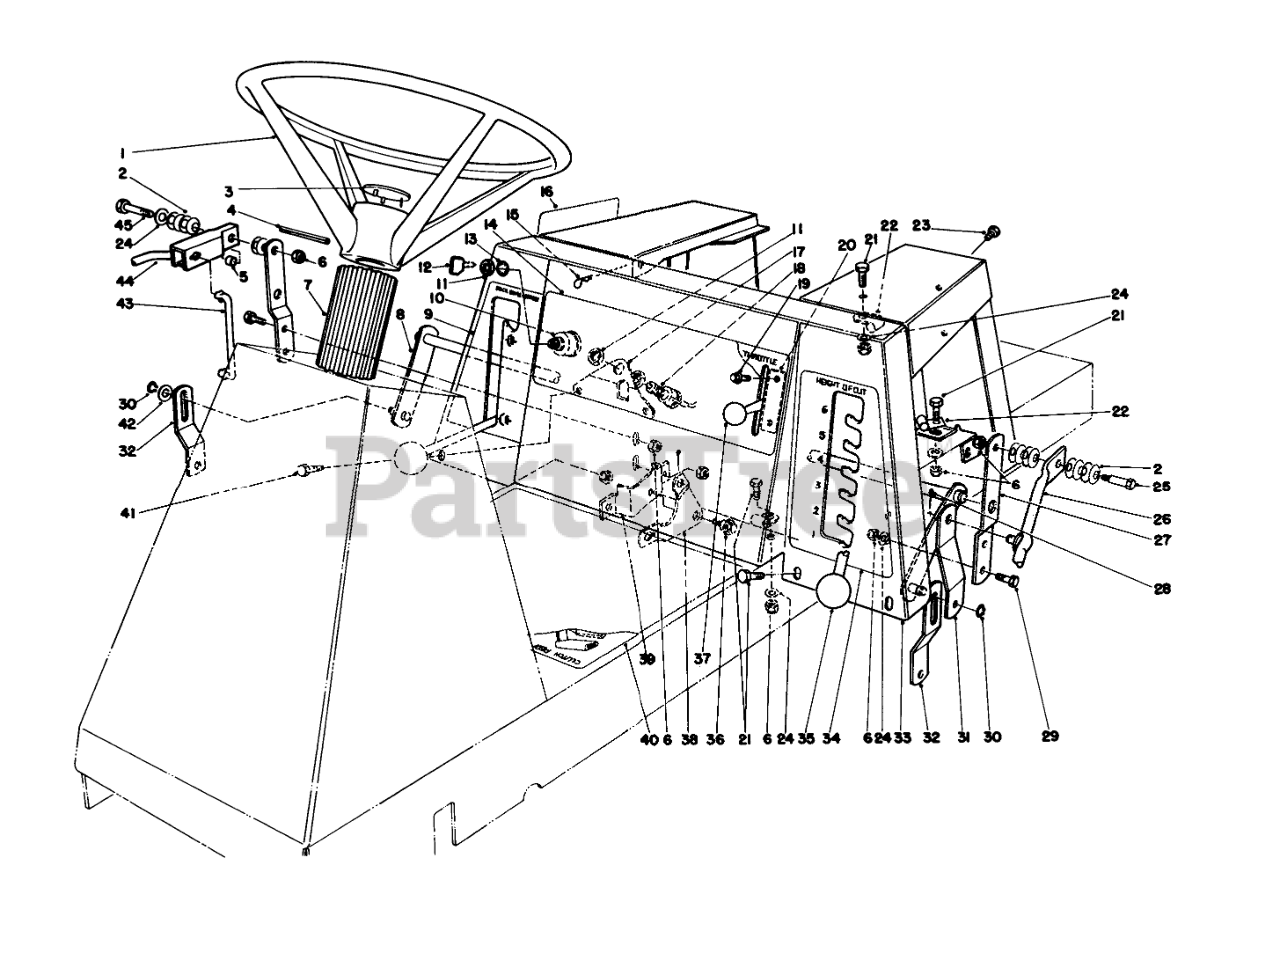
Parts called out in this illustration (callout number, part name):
1	Steering Wheel Assembly (Incl. Ref. #3)
2	WASHER-BELLEVILLE
3	STEERING WHEEL INSERT
4	PIN-ROLL
5	SPACER
6	NUT-LOCK, NI
7	COVER-STEERING SHAFT
8	Arm
9	DECK ENGAGE DECAL
10	Switch-Ignition (Incl. Ref. #11-13)
11	NUT-HH
12	DECAL-HOC, LH
13	WASHER-TOOTH, INTERNAL
14	IGN & THROTTLE DECAL
15	PIN-COTTER
16	DECAL - SHIFT PATTERN
17	SWITCH MT BRKT
18	Switch-Deck (Incl. Ref. #11)
19	SCREW-HWHTF
20	Control-Throttle (Incl. Ref. #37)
21	SCREW-HH
22	CLAMP
23	SCREW-HH
24	WASHER-PLAIN
25	BOLT-SHOULDER
26	HOC LEVER WA B
27	Bracket
28	PIN-COTTER
29	SCREW-HH
30	RING-RETAINING
31	HOC ENGAGE BRKT R
32	Link-Deck Suspension
33	Body-Seat
34	HOC DECAL
36	SCREW-SHOULDER
37	Knob
38	DECK ENGAGE BELLCRANK
39	BELLCRANK MTG BRKT
40	INSTRUCTION DECAL
41	SCREW-HH
42	WASHER-FLAT
43	BELLCRANK LINK(PLTD)
44	SHIFT LEVER WA B
45	SCREW-HH
